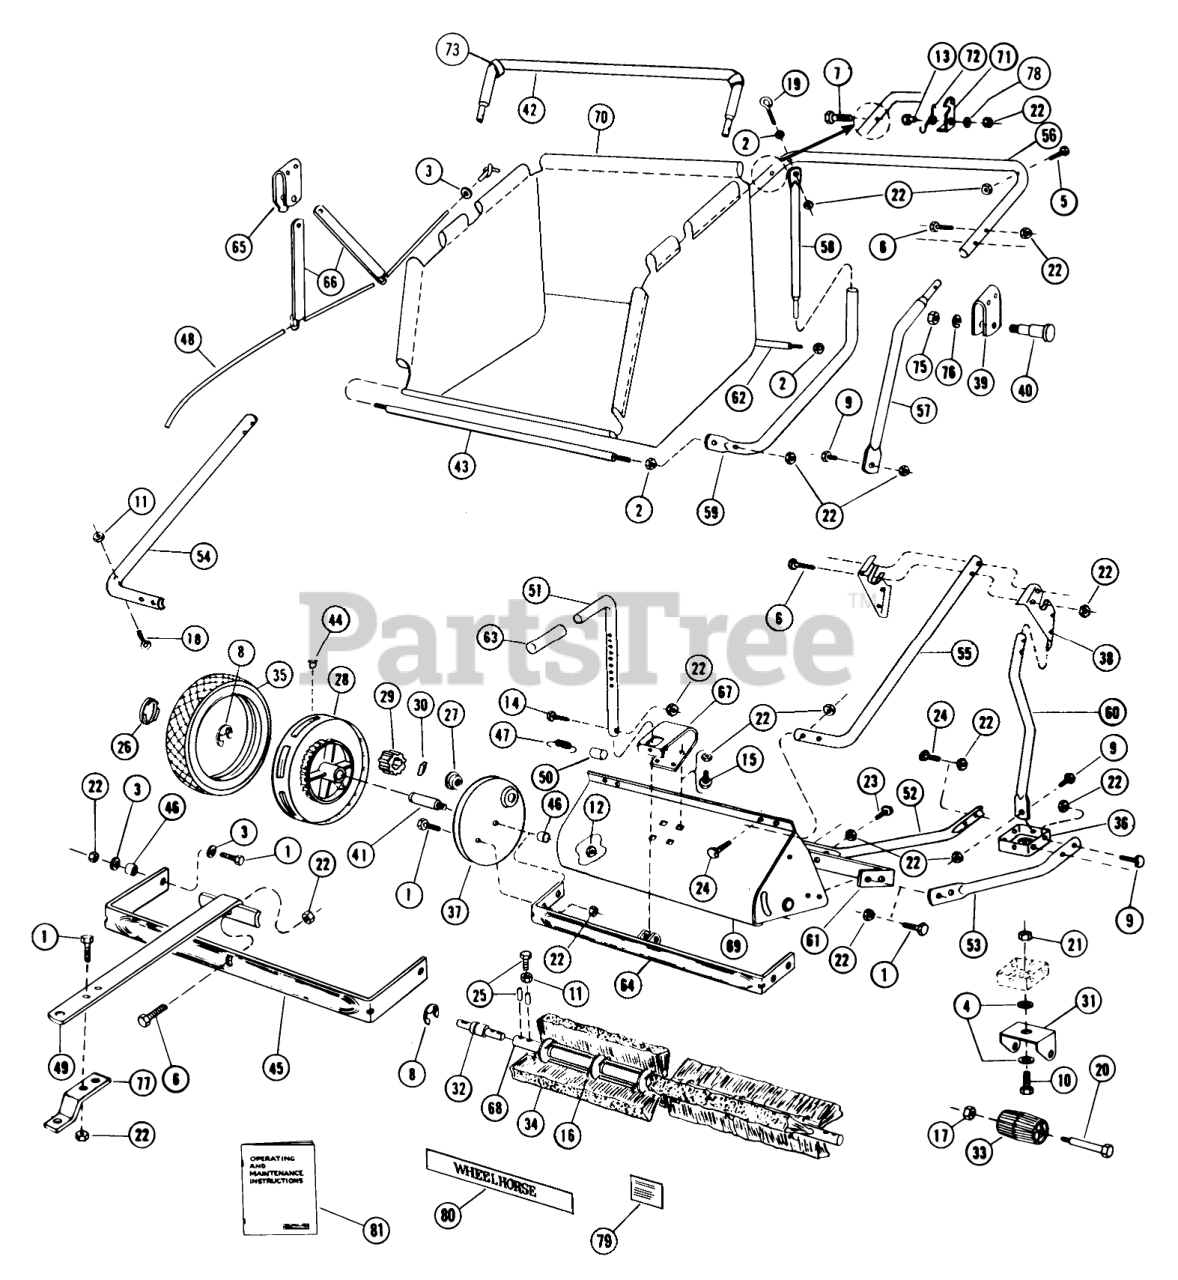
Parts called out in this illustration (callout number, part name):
1	Bolt
2	Nut
3	WASHER 5/16 SAE
4	Washer
5	Bolt
6	Bolt
7	Bolt
8	RING LAM L 262
9	H H C S
10	Bolt
11	Nut
12	NUT-6
13	Bolt Nut 5/16-18
14	HHCS
15	Bolt-Carriage 5/16-18 x 5/8
16	SPRING
17	NUT-6
18	Bolt-Eye 1/4-20 x 2
19	Bolt-Eye 5/16-18 x 2 3/4
20	STUD CASTER
21	Eslok Nut
22	Nut
23	Bolt-Tube 5/16-18 x 1 1/4
25	ROLLPIN 3/16 X 7/8
25	Bolt
26	PLUG BUTTON
27	BEARING
28	Wheel Ass-y.
29	PINION GEAR
30	PINION PAWL
31	Bracket-Caster
32	BRUSH STUB AXLE
32	AXLE BRUSH STUD
33	CASTER ROLLER
34	STRIP
34	STRIP BRUSH
35	Tire 10 x 2.25
36	Caster, Plate Ass-y.
37	SHIELD WHEEL
38	Bracket-Frame Pivot
39	Bracket-Hamper Pivot
40	PIVOT PIN
41	WHEEL STUD
42	Tube-Pivot Stand
43	Rod-Hamper Tie
44	Oiler
45	Hitch-U Bar
46	Spacer
47	Spring-Adjustment
48	Dump Rope
49	Tongue-Hitch
50	TUBE SPRING
51	TUBE ADJUSTING
52	Brace-Pivot Stand
54	Tube R.H. Support
55	Tube L.H. Support
56	Tube Top Hamper
57	Tube Side Hamper
59	Tube Bottom
60	Support R.H. Pivot
60	Support L.H. Pivot
61	Stiffner-Bar
62	Rod-Rear Hamper
64	Bumper Ass-y.
65	ASSY BRACKET
66	Lever-Dump
67	Bracket-Adjustment
68	ASSY BRUSH AXLE & DS
68	Axle-Brush
69	Shield-Ass-y.
70	HAMPER ASSY
70	Hamper-Ass-y.
71	Latch-Hamper
72	Spring-Latch
73	Sleeve-Rubber
75	NUT-6
76	LOCKWASHER
77	BRACKET-HITCH PIN
78	Washer, 7/16
79	Decal Adjustment
80	DECAL-WHEEL HORSE
81	Operating and Maintenance Instructions
